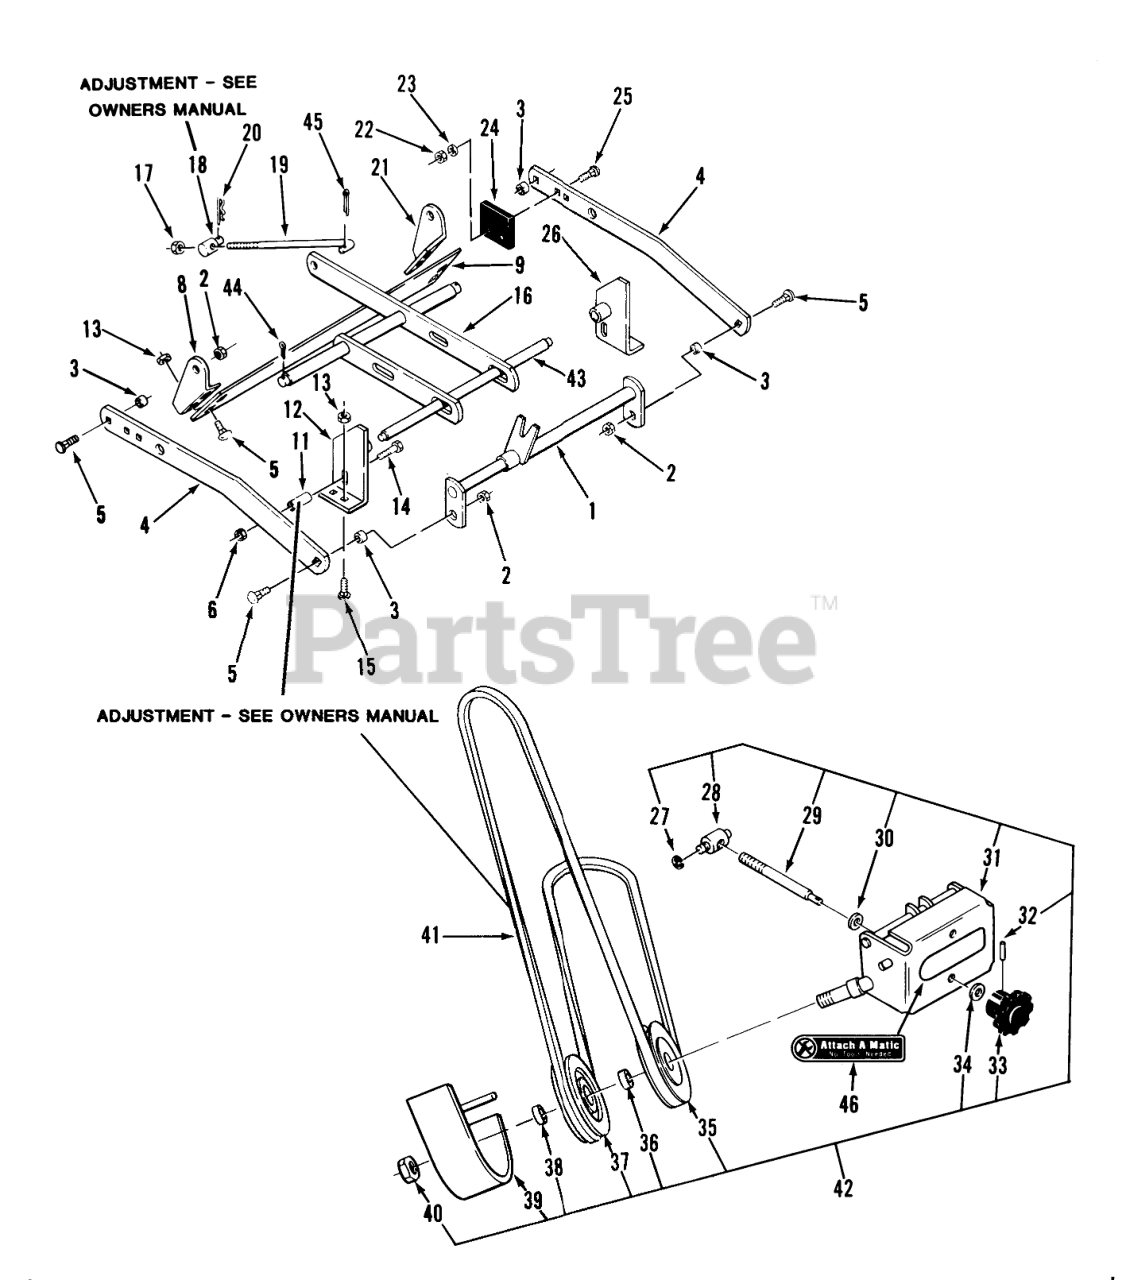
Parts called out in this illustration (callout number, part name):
1	Hitch
2	LOCKNUT-FLANGE
3	SPACER
4	Bar Draft
5	Bolt
6	Nut
8	Bracket-Rt. Rear
8	Bracket-R.H.
9	PLATE
11	PLATE R
12	Bracket-R.H.
13	NUT
14	CARRIAGE BOLT -4
15	Bolt
16	Leveler
17	NUT
18	TRUNNION-LIFT
19	Lift Rod
20	Hairpin
21	Bracket-L.H. Rear
21	Bracket-L.H.
22	Nut
23	Collar
24	BUMPER
25	Bolt-Carriage
26	Bracket-L.H.
27	RING-RETAINING
28	TRUNNION-DOUBLE
29	ROD ADJ
30	Washer
31	Front Support
32	PIN-ROLL
33	KNOB-ADJUSTMENT
34	WASHER-SPRING
35	Pulley-V
36	SPACER
37	PULLEY-FLAT IDLER
38	SPACER-OUTER
39	Belt Cover
40	Nut
41	V-BELT
42	ASM-SUPPORT,IDLER
43	Front Shaft
44	Cotter Pin
45	Cotter Pin
46	Decal-Attac-O-Matic
